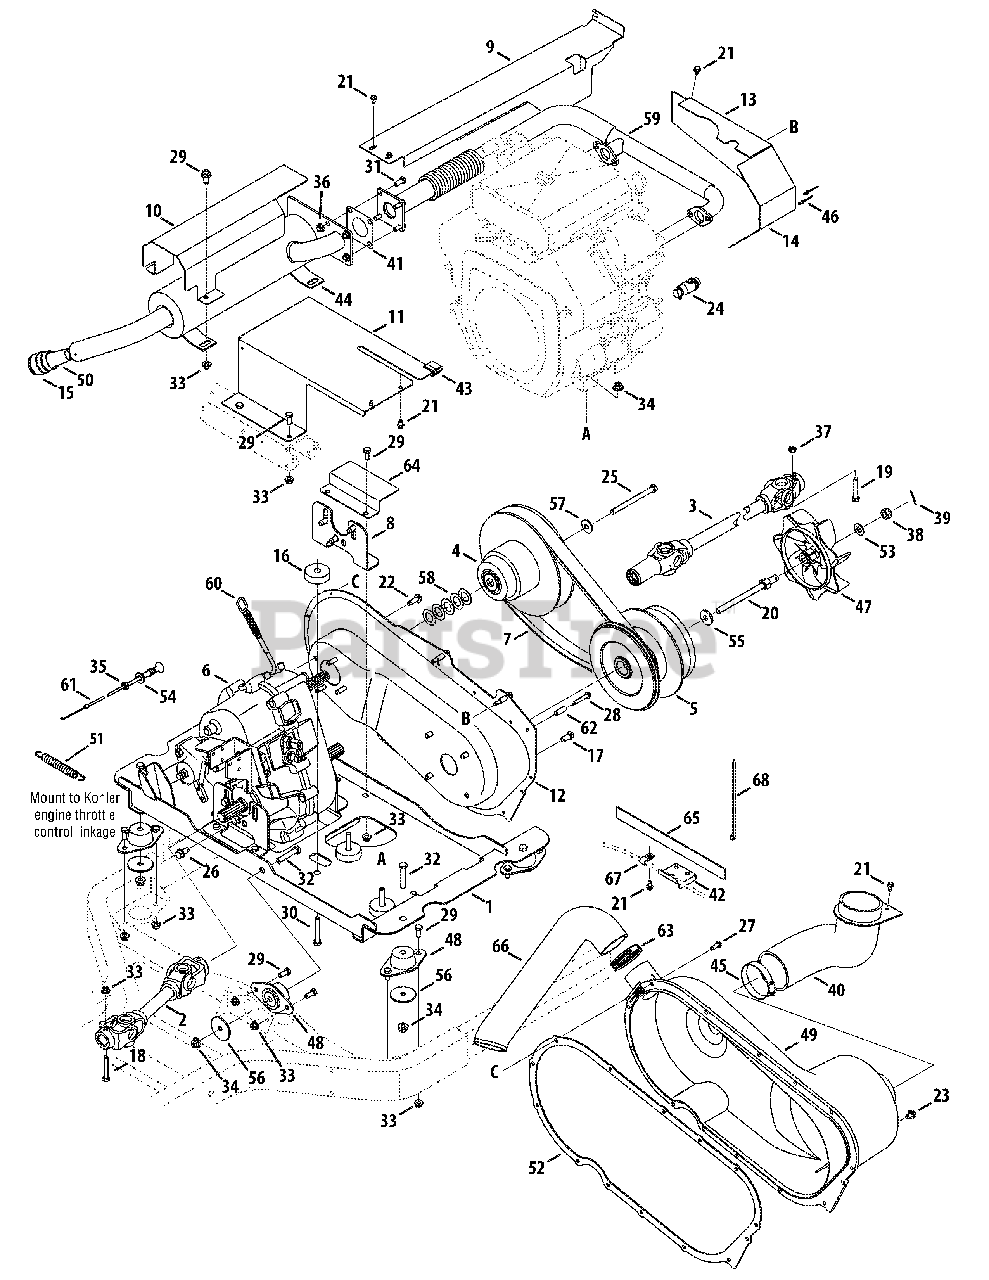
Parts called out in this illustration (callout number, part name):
1	Tray Assembly, Engine, Kohler
2	Shaft Assembly, Rr/prop
3	Shaft Assembly, Frt/prop, Hilliard
4	Clutch Assembly, Cvt, Driven
5	Clutch Assembly, Cvt, Driver, Cvr
6	Case Assembly, Transfer
7	Belt, Cvt, 4x4
8	Bracket, Trans, Mount
9	Cover, Heat, Shield
10	Exhaust, Shield, Heat
11	Shroud, Engine, Kohler
12	Cover, Back, Kohler
13	Cover, Engine, Kohler
14	Cover, Engine, Rr, Kohler
16	Spacer, Engine, Kohl
17	Hex Head Screw, 3/8-16, .75
18	Hex Head Screw, 5/16-18, 2.00
19	Hex Head Screw, 5/16-18, 1.875
20	Hex Head Screw, 7/16-20, 5.00
21	Screw, Tt, 1/4-20, 0.500
22	Screw, Tt, 5/16-18, .875
23	Screw, B, 5/16-12, 0.500
25	Hex Head Screw, 3/8-24, 3.50
26	Screw, Tt, 3/8-16, 0.750
27	Screw, Tt, 1/4-20, 0.750
28	Screw, Tt, 1/4-20, 1.625
29	Hex Head Screw, 5/16-18, .75
30	Hex Head Screw, 3/8-16, 2.25
31	Hex Head Screw, 5/16-18, .875
32	Hex Head Screw, 3/8-16, 2.00
33	Nut, Flange Lock, 5/16-18, Nylon
34	Nut, Flange Lock, 3/8-16, Nylon
35	Nut, Jam, 3/8-24
36	Nut, Flange Lock, 5/16-18
37	Nut, Hex Lock, 5/16-18, Ctrlk
38	Nut, Hex, 1/2-20, Gr5, Slot
39	Pin, Cot, 3/32, 1.0
40	Tube, Cvt, Intake
41	Gasket, Engine
42	Bracket, Cable Shield
43	Heat Baffle Seal
45	Clamp, Hose, Adj.
46	Rivet, Pop, .125 Od, #42
47	Impeller, Blo
48	Compression Mount, Eng, Head
49	Cover, Cvt
50	Spark Arrester Screen
51	Spring Latch
52	Seal, CVT, Cover
53	Washer, Flat, .510 x 1.00 x .060
54	Washer, Flat, .406 x .875 x .059
55	Washer, Flat, .450 x 1.250 x .164
56	Washer, Flat, .38 x 2.00 x .12
57	Washer, Bell, .396 x 1.140 x .095
58	Washer, Flat, .793 x 1.368 x .025
59	Pipe, Exhaust, Kohl
60	Cable, Throttle Control, Kohler
61	Cable, Choke Control, Kohl
62	Spacer, .260 Id x .375od x 1.0l
63	Clamp, Hose
64	Shield, Harness
65	Heat Shield Sleeve
66	Hose, CVT, Exhaust
67	Clamp, Hose
68	Tie, Cable
